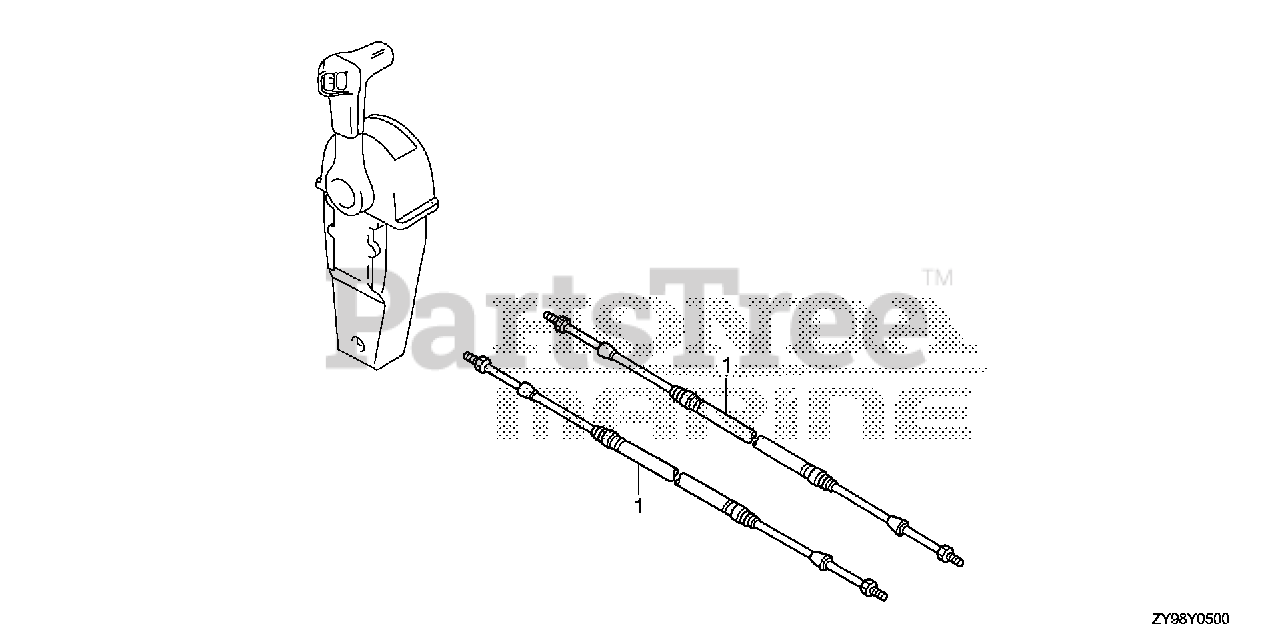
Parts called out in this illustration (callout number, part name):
1	CABLE, REMOTE CONTROL (10') (LOW FRICTION)
1	CABLE ASSY., PUSH-PULL (33C-5FT)
1	CABLE, REMOTE CONTROL (11') (LOW FRICTION)
1	CABLE ASSY., PUSH-PULL (33C-6FT)
1	CABLE, REMOTE CONTROL (12') (LOW FRICTION)
1	CABLE ASSY., PUSH-PULL (33C-7FT)
1	CABLE, REMOTE CONTROL (13') (LOW FRICTION)
1	CABLE ASSY., PUSH-PULL (33C-8FT)
1	CABLE, REMOTE CONTROL (14') (LOW FRICTION)
1	CABLE ASSY., PUSH-PULL (33C-9FT)
1	CABLE, REMOTE CONTROL (15') (LOW FRICTION)
1	CABLE ASSY., PUSH-PULL (33C-10FT)
1	CABLE, REMOTE CONTROL (16') (LOW FRICTION) (NOT AVAILABLE)
1	CABLE ASSY., PUSH-PULL (33C-11FT)
1	CABLE, REMOTE CONTROL (17') (LOW FRICTION)
1	CABLE ASSY., PUSH-PULL (33C-12FT)
1	CABLE, REMOTE CONTROL (18') (LOW FRICTION) (NOT AVAILABLE)
1	CABLE ASSY., PUSH-PULL (33C-13FT)
1	CABLE, REMOTE CONTROL (19') (LOW FRICTION)
1	CABLE ASSY., PUSH-PULL (33C-14FT)
1	CABLE, REMOTE CONTROL (20') (LOW FRICTION) (NOT AVAILABLE)
1	CABLE ASSY., PUSH-PULL (33C-15FT)
1	CABLE, REMOTE CONTROL (21') (LOW FRICTION)
1	CABLE ASSY., PUSH-PULL (33C-16FT)
1	CABLE, REMOTE CONTROL (22') (LOW FRICTION) (NOT AVAILABLE)
1	CABLE ASSY., PUSH-PULL (33C-17FT)
1	CABLE, REMOTE CONTROL (23') (LOW FRICTION)
1	CABLE ASSY., PUSH-PULL (33C-18FT)
1	CABLE, REMOTE CONTROL (24') (LOW FRICTION) (NOT AVAILABLE)
1	CABLE ASSY., PUSH-PULL (33C-19FT)
1	CABLE, REMOTE CONTROL (25') (LOW FRICTION)
1	CABLE ASSY., PUSH-PULL (33C-20FT)
1	CABLE, REMOTE CONTROL (26') (LOW FRICTION)
1	CABLE ASSY., PUSH-PULL (33C-21FT)
1	CABLE, REMOTE CONTROL (27') (LOW FRICTION)
1	CABLE ASSY., PUSH-PULL (33C-22FT)
1	CABLE, REMOTE CONTROL (28') (LOW FRICTION) (NOT AVAILABLE)
1	CABLE ASSY., PUSH-PULL (33C-23FT)
1	CABLE, REMOTE CONTROL (29') (LOW FRICTION)
1	CABLE ASSY., PUSH-PULL (33C-24FT)
1	CABLE, REMOTE CONTROL (30') (LOW FRICTION) (NOT AVAILABLE)
1	CABLE ASSY., PUSH-PULL (33C-25FT)
1	CABLE, REMOTE CONTROL (31') (LOW FRICTION)
1	CABLE ASSY., PUSH-PULL (33C-26FT)
1	CABLE, REMOTE CONTROL (32') (LOW FRICTION) (NOT AVAILABLE)
1	CABLE ASSY., PUSH-PULL (33C-27FT)
1	CABLE, REMOTE CONTROL (33') (LOW FRICTION)
1	CABLE ASSY., PUSH-PULL (33C-28FT)
1	CABLE, REMOTE CONTROL (34') (LOW FRICTION) (NOT AVAILABLE)
1	CABLE ASSY., PUSH-PULL (33C-29FT)
1	CABLE, REMOTE CONTROL (35') (LOW FRICTION)
1	CABLE ASSY., PUSH-PULL (33C-30FT)
1	CABLE ASSY., PUSH-PULL (33C-31FT)
1	CABLE ASSY., PUSH-PULL (33C-32FT)
